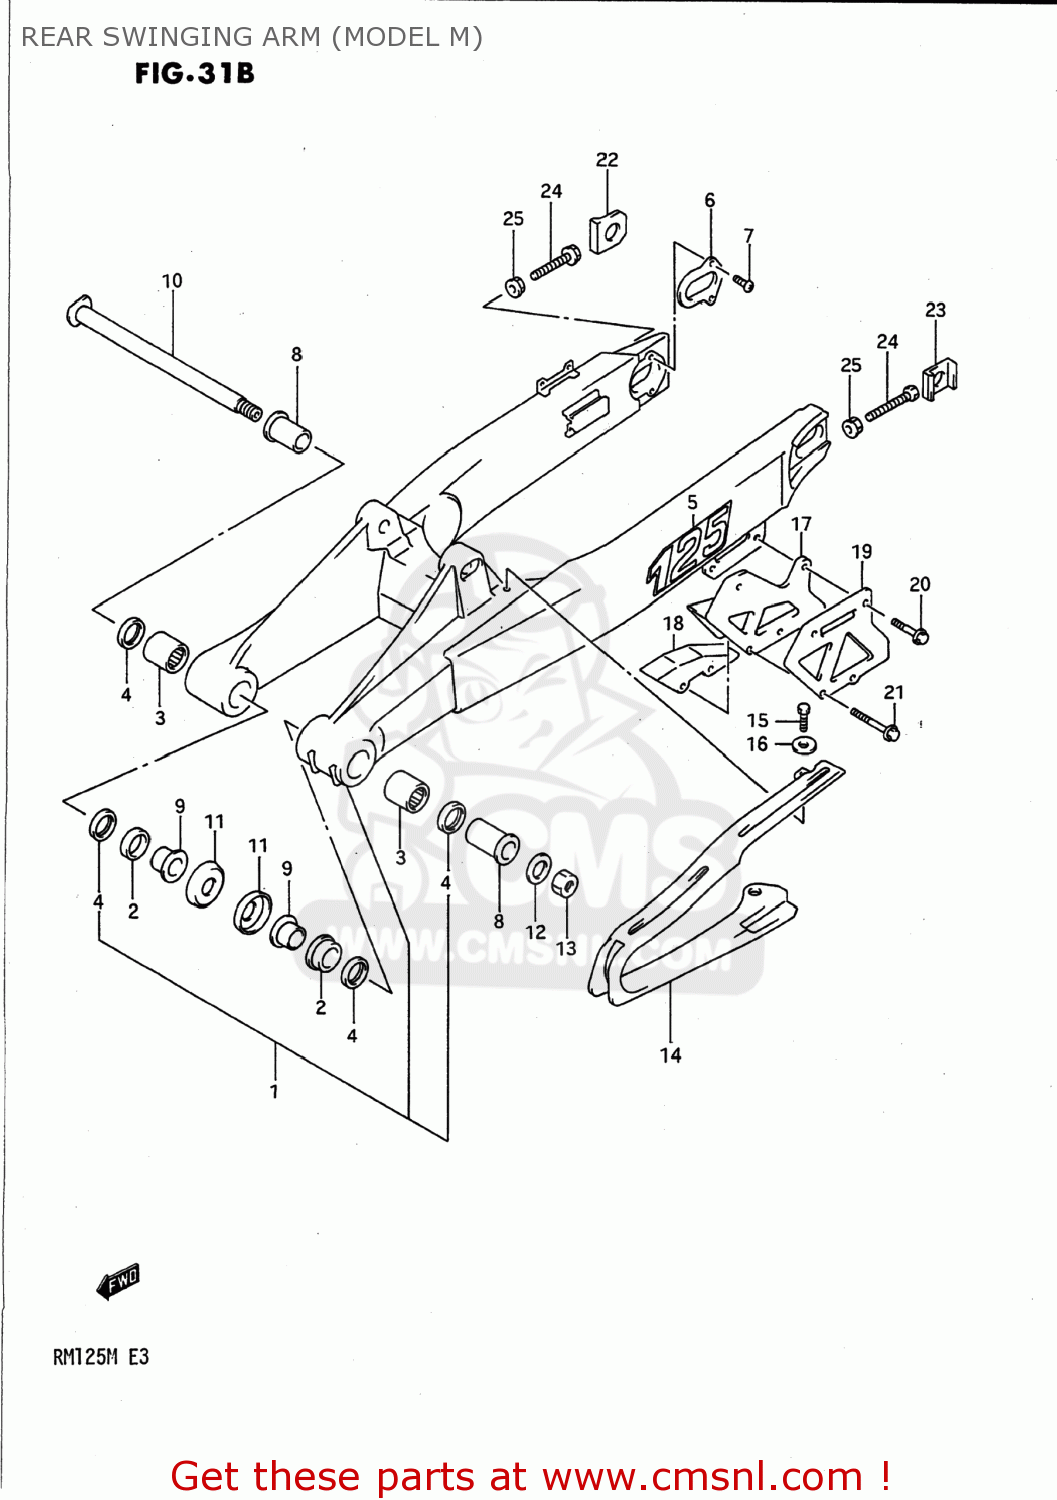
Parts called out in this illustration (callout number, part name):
1	SWING ARM ASSEMBLY,REAR
2	BUSHING,SWGARM PIVOT
3	BEARING(20X27X30)
4	OIL SEAL
5	EMBLEM,SWING ARM
6	PLATE,INNER
7	SCREW (5X8)
8	SPACER,RR SWGARM PIVOT
9	SPACER,SWGARM PIVOT INNER
10	SHAFT,RR SWINGINGARM PIVOT
11	COVER,SWGARM PIVOT
12	WASHER(14.2X24X2.3)
13	NUT
14	BUFFER,CHAIN TOUCH DEFENSE
15	BOLT
16	WASHER
17	GUIDE,CHAIN
18	DEFENSE,CHAIN GUIDE
19	PLATE,CHAIN GUIDE,OUTER
20	BOLT
21	SCREW(6X40)
22	WASHER,CHAIN ADJUSTER
23	WASHER,CHAIN ADJUSTER
24	BOLT(8X50)
25	NUT
